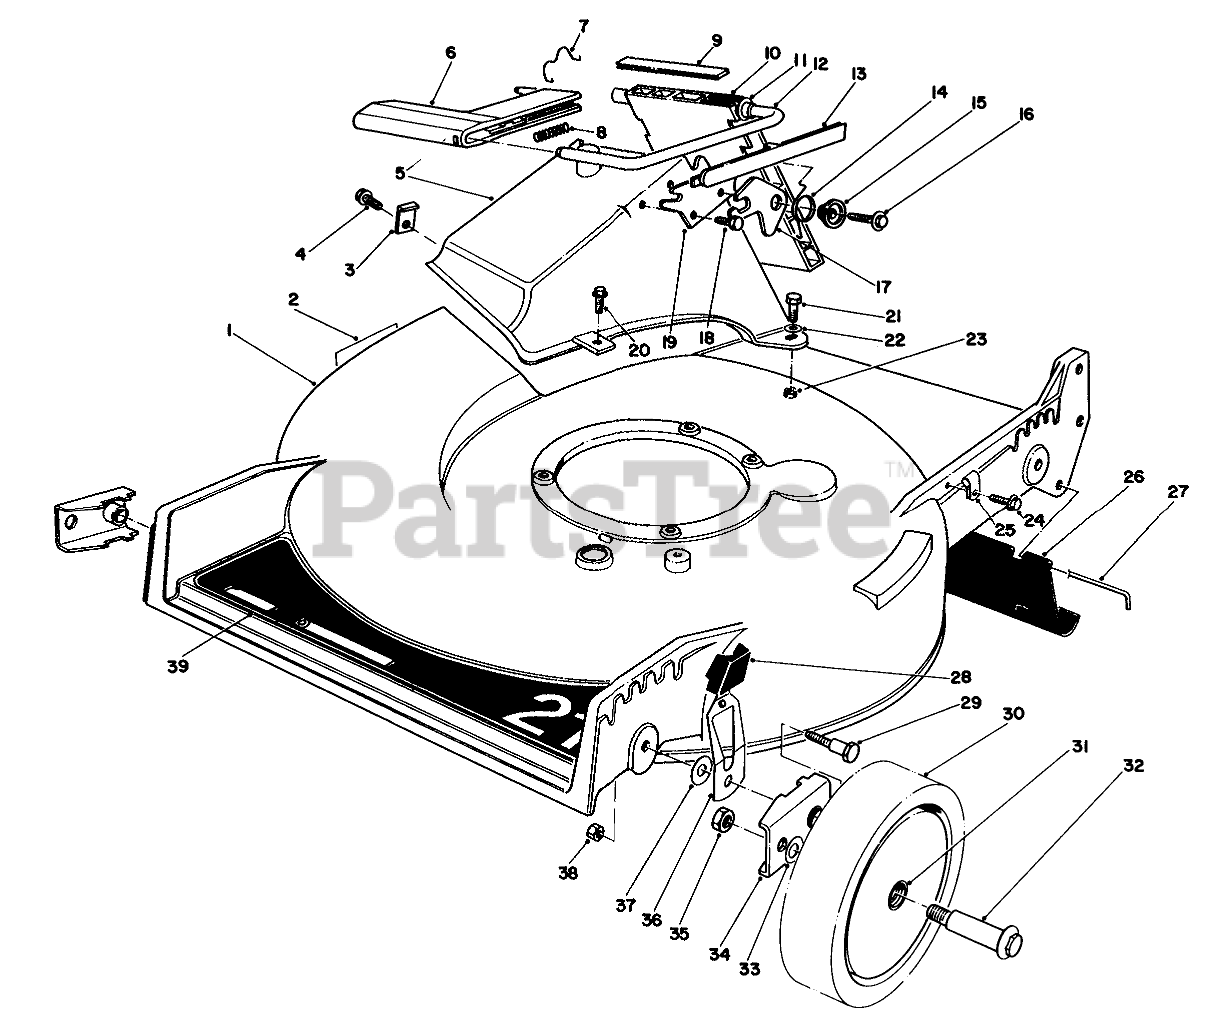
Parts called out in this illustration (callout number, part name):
1	Housing (Incl. Ref. #2)
2	DECAL-DANGER
3	TUNNEL CLIP
4	SCREW
5	Tunnel Discharge
6	Handle-Door
7	DOOR RET SPRING
8	Spring
9	DOOR COVER
10	Door Discharge
11	BUSHING-NYLON
12	DOOR ROD +
13	DOOR HANDLE COVER
14	TORSION SPRING
15	DOOR SPACER
16	SCREW-HWH
17	SAFETY LATCH
18	SCREW-PLASTITE
19	DOOR LATCH PLATE
20	Screw
21	SCREW-HH
22	WASHER-FLAT
23	NUT-LOCK, NI
24	SCREW
25	CLAMP-CABLE
26	SHIELD-TRAILING
27	ROD-SHIELD
28	KNOB-ARM
29	PIVOT SCREW
30	Wheel & Tire Assembly (Incl. Ref. #31)
31	BUSHING
32	BOLT-WHEEL
33	WASHER
34	HP PIVOT ARM ASM
35	Nut
36	Spring Arm
37	WASHER-PIVOT
38	NUT-LOCK, NI
39	DECK DECAL
